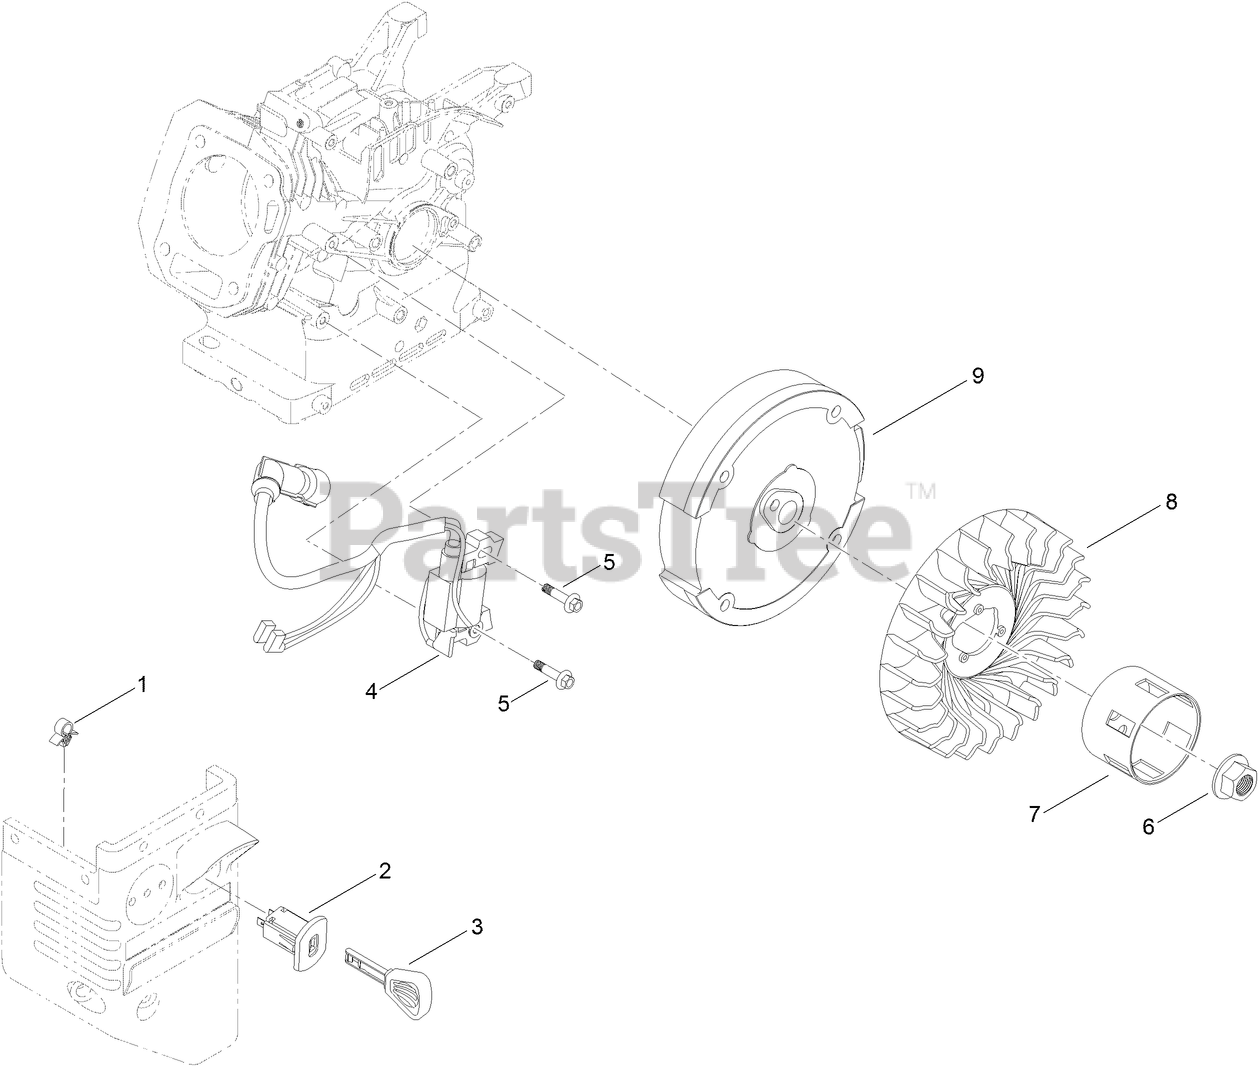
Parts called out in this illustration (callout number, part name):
2	SWITCH-KEY
4	IGNITION COIL ASM
5	SCREW-HHF
6	NUT-FLANGE
7	CUP-STARTER
9	FLYWHEEL-RECOIL
